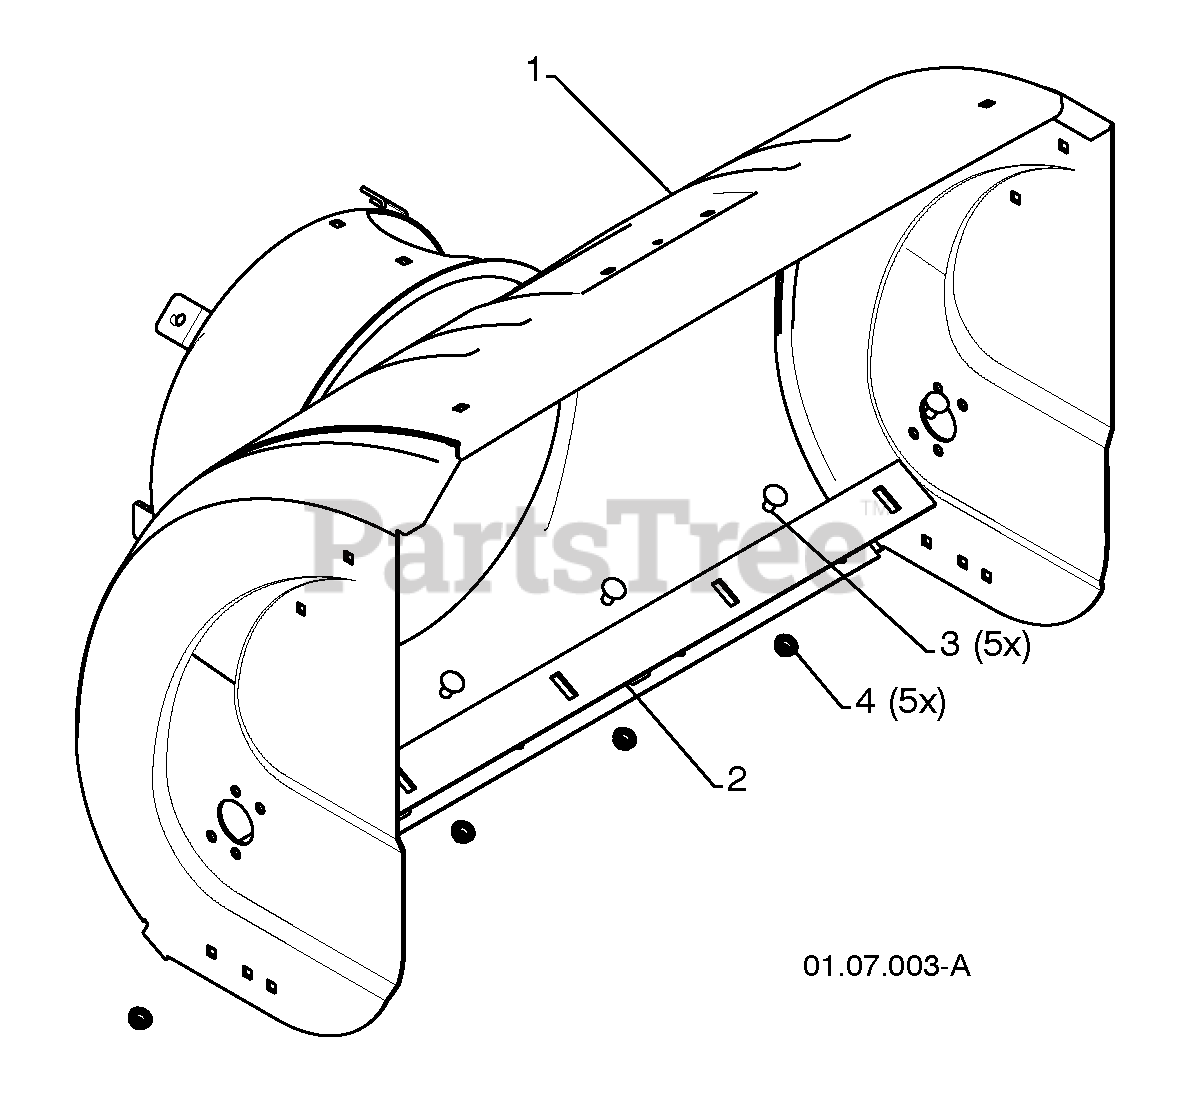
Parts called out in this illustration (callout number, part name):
1	AUGER HOUSING
2	SCRAPPER BAR
3	CARRIAGE BOLT 5/16-18 X .625
4	NUT 5/16-18
